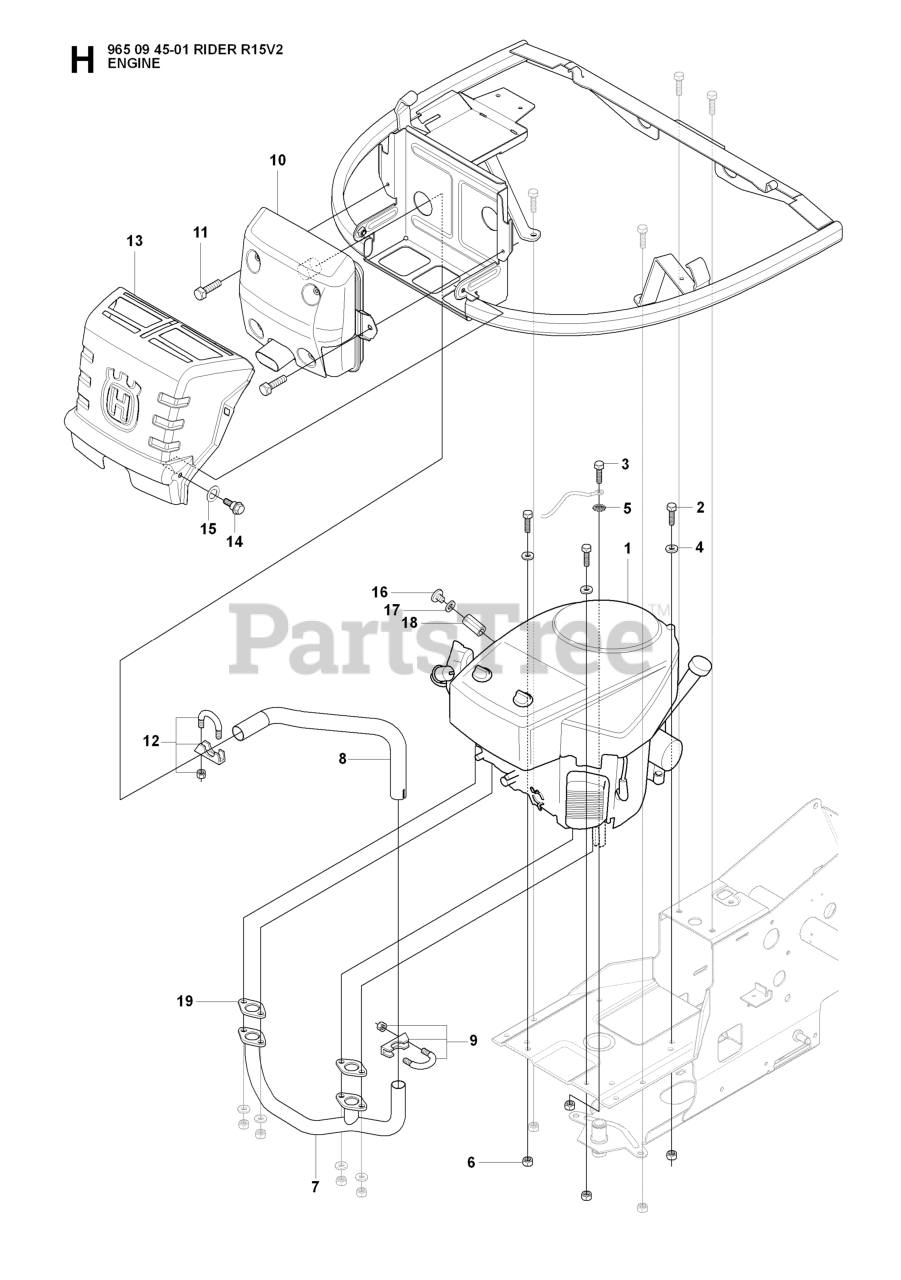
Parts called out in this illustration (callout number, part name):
4	WASHER BRB 8.4X17
6	LOCKNUT M8
8	PIPE KAWASAKI
9	CLAMP
12	CLAMP
13	HEAT PROTECTOR
15	SPRINGWASHER
